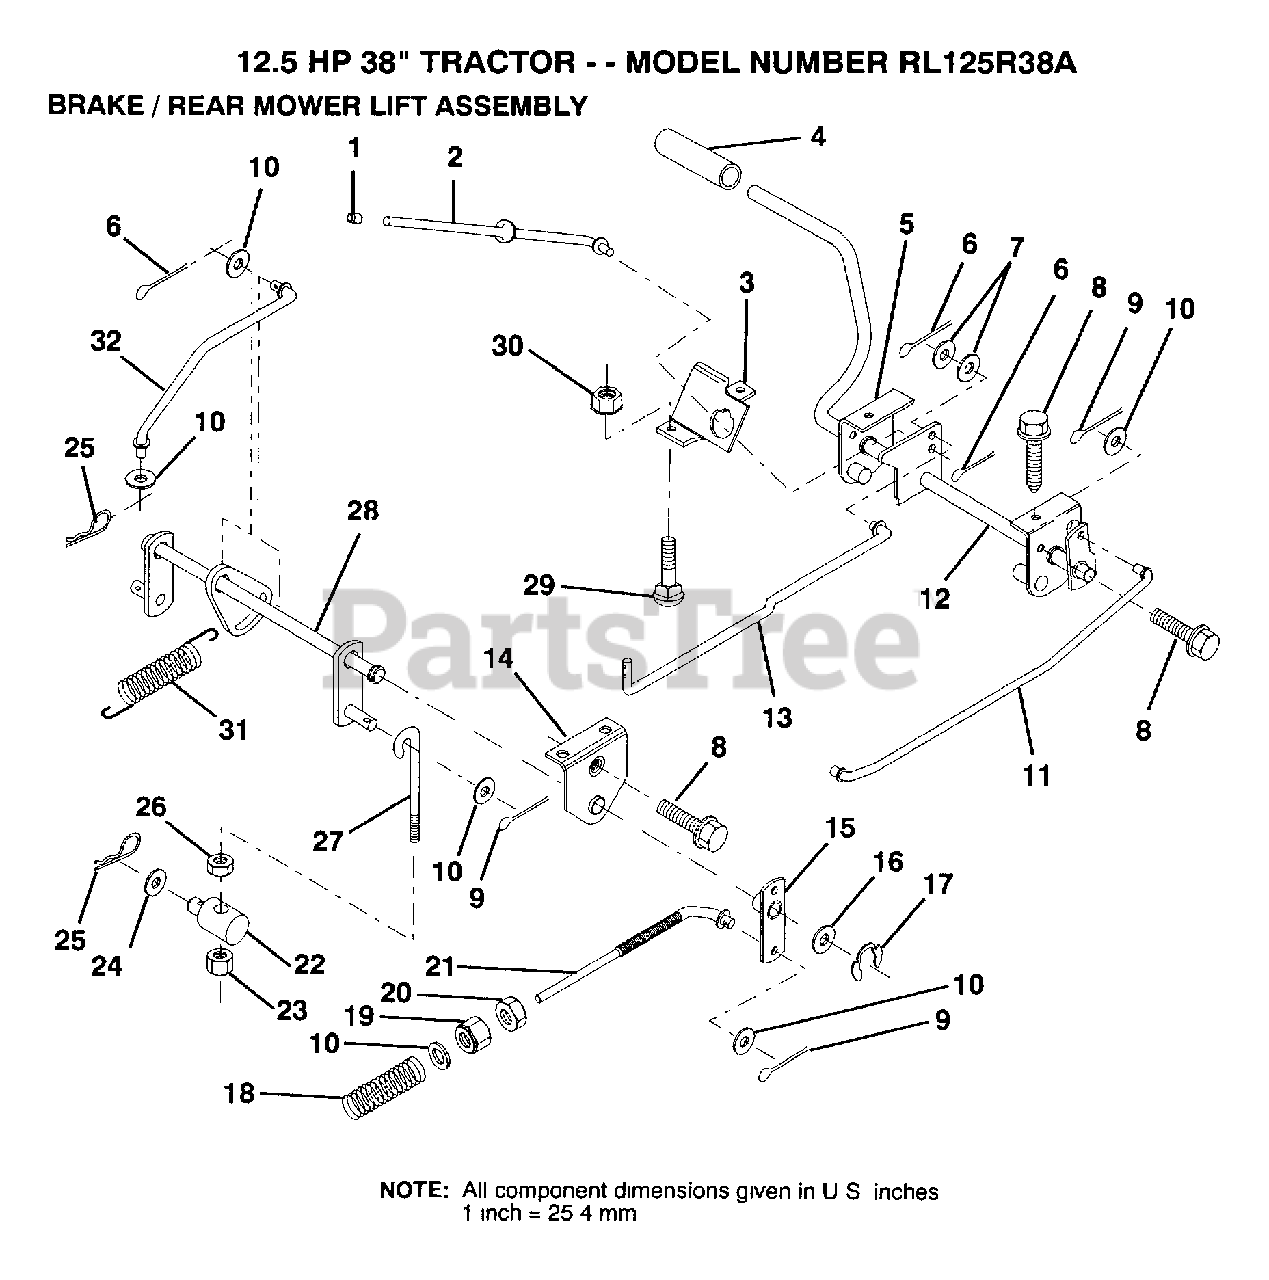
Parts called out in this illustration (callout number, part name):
1	PLUNGER CAP T
2	"ROD,PARK BRAKE"
3	"BRKT,PARK BRAKE"
4	PEDAL COVER T
5	BRK ASM CLUT LH
7	WASHER
8	SCREW LT
9	COTTER PIN
10	WASHER
11	"ROD,FRT BRAKE"
12	ASM CLUTCH/BRK PD
13	"ROD,CLUTCH"
14	"BRKT,LIFT SHAFT"
15	BRAKE PIVOT ARM
16	WASHER T
17	KLIP RING
18	SPRING ROD LT
19	NUT
24	WASHER
25	SPRING.RETAINER
26	LOCKNUT
27	THREADED LINK
28	ASM REAR MOW LIFT
31	COUNTER SPRING
32	LINK LIFT LEVER
